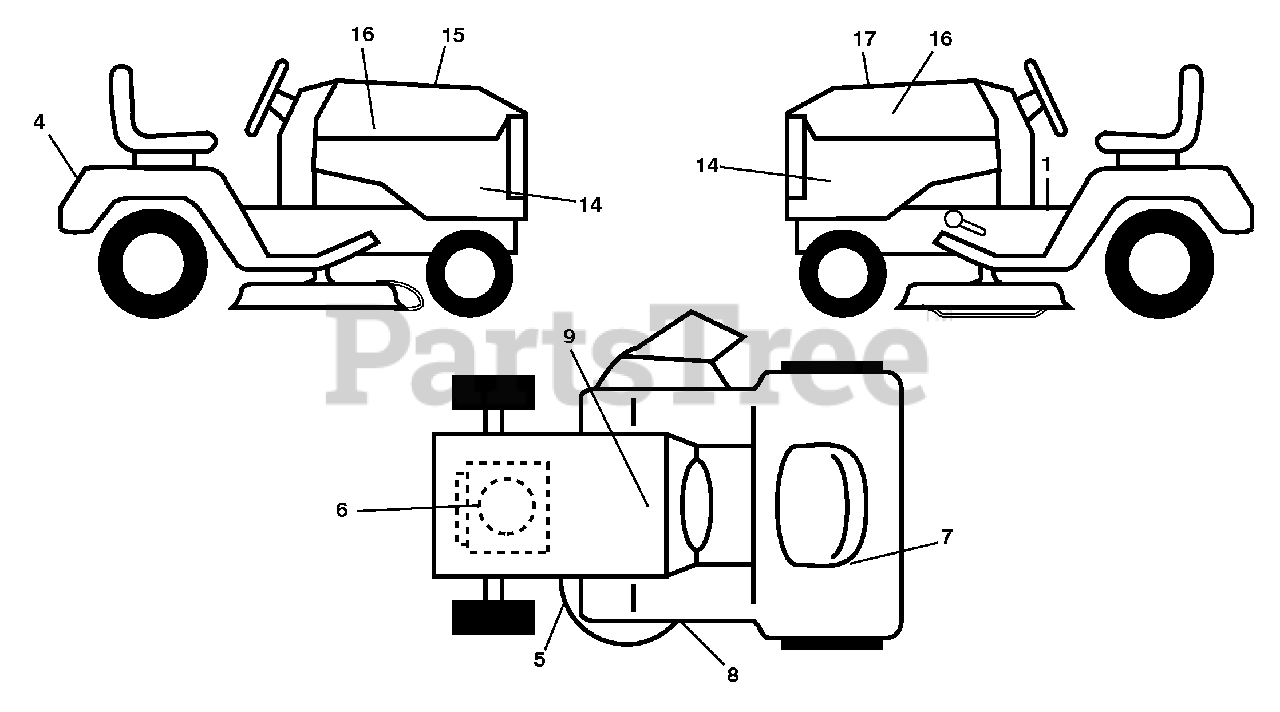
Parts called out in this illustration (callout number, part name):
1	Decal, Operator's
4	Decal, Fender
5	Decal, Caution
6	Decal, Eng. HP
7	Decal, Warning
8	Decal, Mower Sch.
9	Decal, Battery Dnge/Poi
14	Decal, Panel Side
15	Decal, Cust. Resp.
16	Decal, Hood Logo
17	Decal, Replacement
